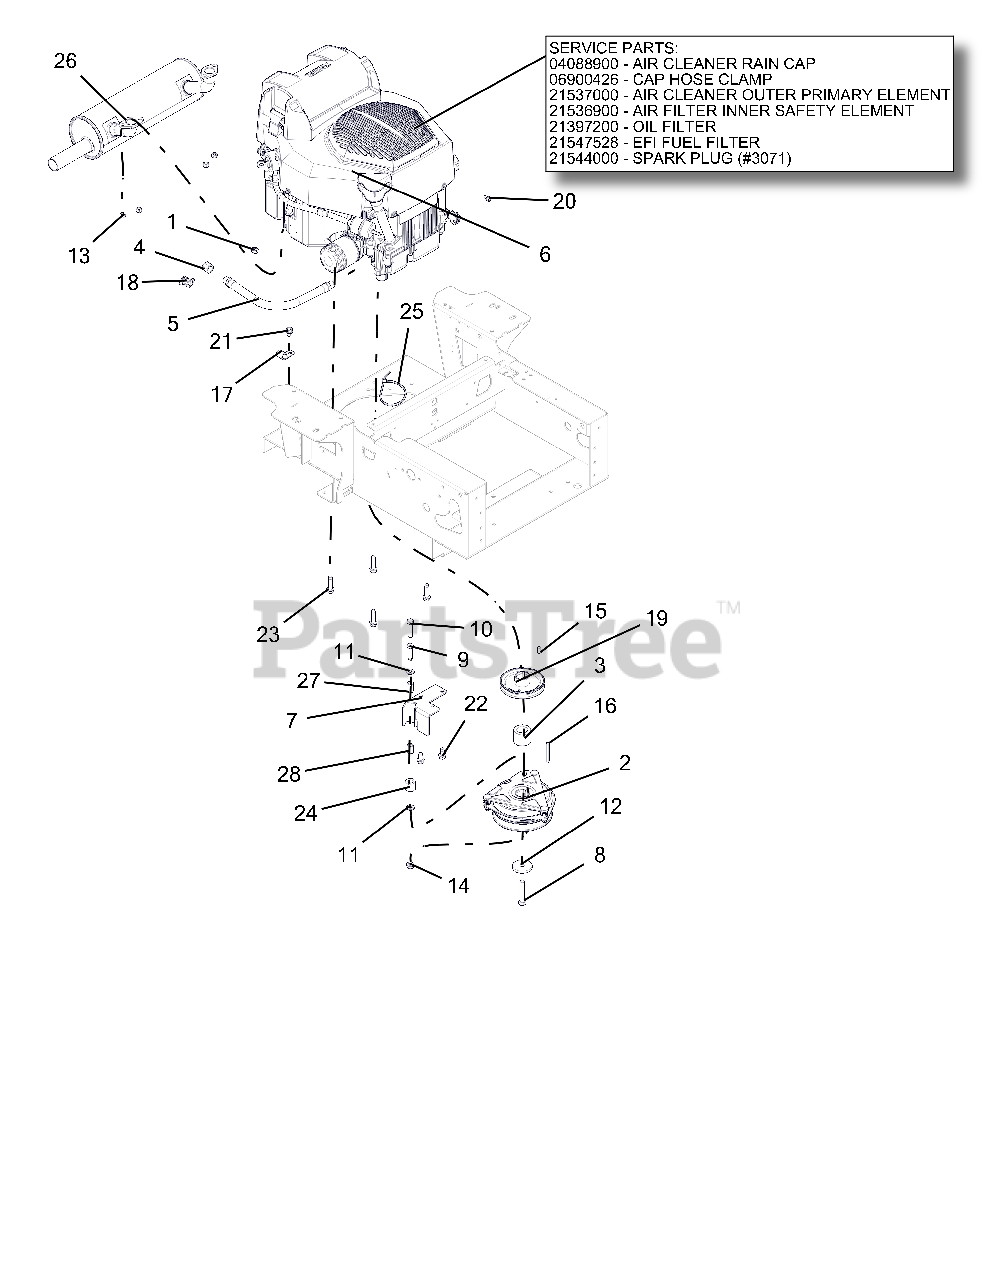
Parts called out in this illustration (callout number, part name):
1	CLAMP, FUEL LINE
2	CLUTCH, OGURA GT2.5-FE02
3	SPCR, 1.125 X 1.75 X 1.400
4	PIPE, CAP 3/8 NPT FEMALE
5	HOSE, HYD .38-11-OK M6N0-M6N0
6	ENGINE, KOHLER ZT730 CONFIDANT
6	AIR CLEANER RAIN CAP
6	CAP HOSE CLAMP
6	AIR CLEANER OUTER PRIMARY ELEMENT
6	AIR FILTER INNER SAFETY ELEMENT
6	OIL FILTER
6	EFI FUEL FILTER
6	SPARK PLUG (#3071)
7	BRKT, CLUTCH STOP
8	BLT-HEX .44-20X2.50 GR5 EP80 YWZC
9	BLT-HEX .38-16X1.50 GR5 YWZC
10	BLT-HEX .38-16X1.75 GR5 YWZC
11	WSHR-FL-STL.406X.812X.065 YWZ
12	WSHR-FL-STL .469X2.00X.25 YWZC
13	NUT-LK-TOP M8-1.25 YWZC
14	NUT, LK-TOP-FLG .38-16 YWZC
15	KEY-SQ .250X.250X.625
16	KEY, .25X.25X2.25
18	CLIP, T, .38-.50
19	PULLEY, 4.50 OD X 1.127 ENGINE-BLACK
20	SCR-TAP .25-20X.50 HWH TR YWZ
21	SCR-TAP .38-16X.50 HWH TR YWZ
22	SCR-TAP .38-16X.75 HWH TR YWZ
23	SCR-TAP .38-16X1.50 HWH TR YZ
24	BUMPER, RUBBER .62 X 1.0 X .88 LG
25	CABLE, TIE 5.50 LG
26	MUFFLER, KOHLER CONFIDANT
27	BUSH.,S.391X.622X.95 ST REV A
28	BUSHING, SLV .407X.625X.813
